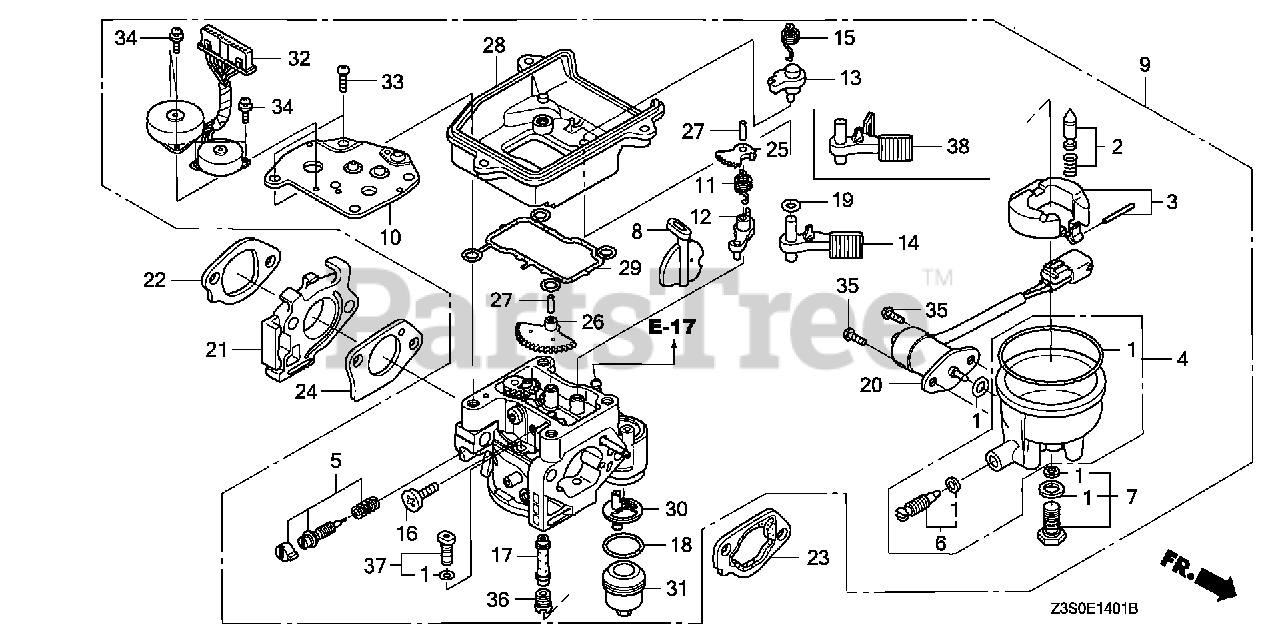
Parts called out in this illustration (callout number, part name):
1	GASKET SET
2	VALVE SET, FLOAT
3	FLOAT SET
4	CHAMBER SET, FLOAT
5	SCREW SET
6	SCREW SET, DRAIN (ADVENTURE GREEN) (CARBURETOR NO.)
7	SCREW SET
8	CHOKE SET (CARBURETOR NO.)
9	CARBURETOR ASSY. (BE89N B)
10	PLATE, MOTOR (CARBURETOR NO.)
11	SPRING, CHOKE RELIEF ARM RETURN
12	ARM, CHOKE RELIEF (CARBURETOR NO.)
13	ARM, MANUAL START
15	SPRING, MANUAL START LEVER RETURN
16	SCREW, THROTTLE STOP
17	NOZZLE, MAIN
18	GASKET, FUEL STRAINER CUP
19	O-RING (CARBURETOR NO.)
20	VALVE ASSY., SOLENOID
21	INSULATOR, CARBURETOR
22	GASKET, INSULATOR
23	SPACER, CARBURETOR
24	GASKET, CARBURETOR
25	GEAR, CHOKE REDUCTION
26	GEAR, MIDDLE
27	SHAFT, GEAR CENTER
28	CASE, MOTOR
29	GASKET, MOTOR CASE
30	FILTER, CUP
31	CUP, FUEL STRAINER
32	MOTOR, THROTTLE & CHOKE CONTROL
33	SCREW, PAN (5X20)
34	SCREW-WASHER (3X6)
35	SCREW-WASHER (5X12)
36	JET, MAIN (#98) Use from Engine SN BE87A A to BE87A A.
36	JET, MAIN (#100) Use from Engine SN BE87A A to BE87A A.
36	JET, MAIN (#102) (ADVENTURE GREEN) (CARBURETOR NO.)
37	JET SET, PILOT (#45) (CARBURETOR NO.)
38	LEVER, MANUAL START (CARBURETOR NO.)
